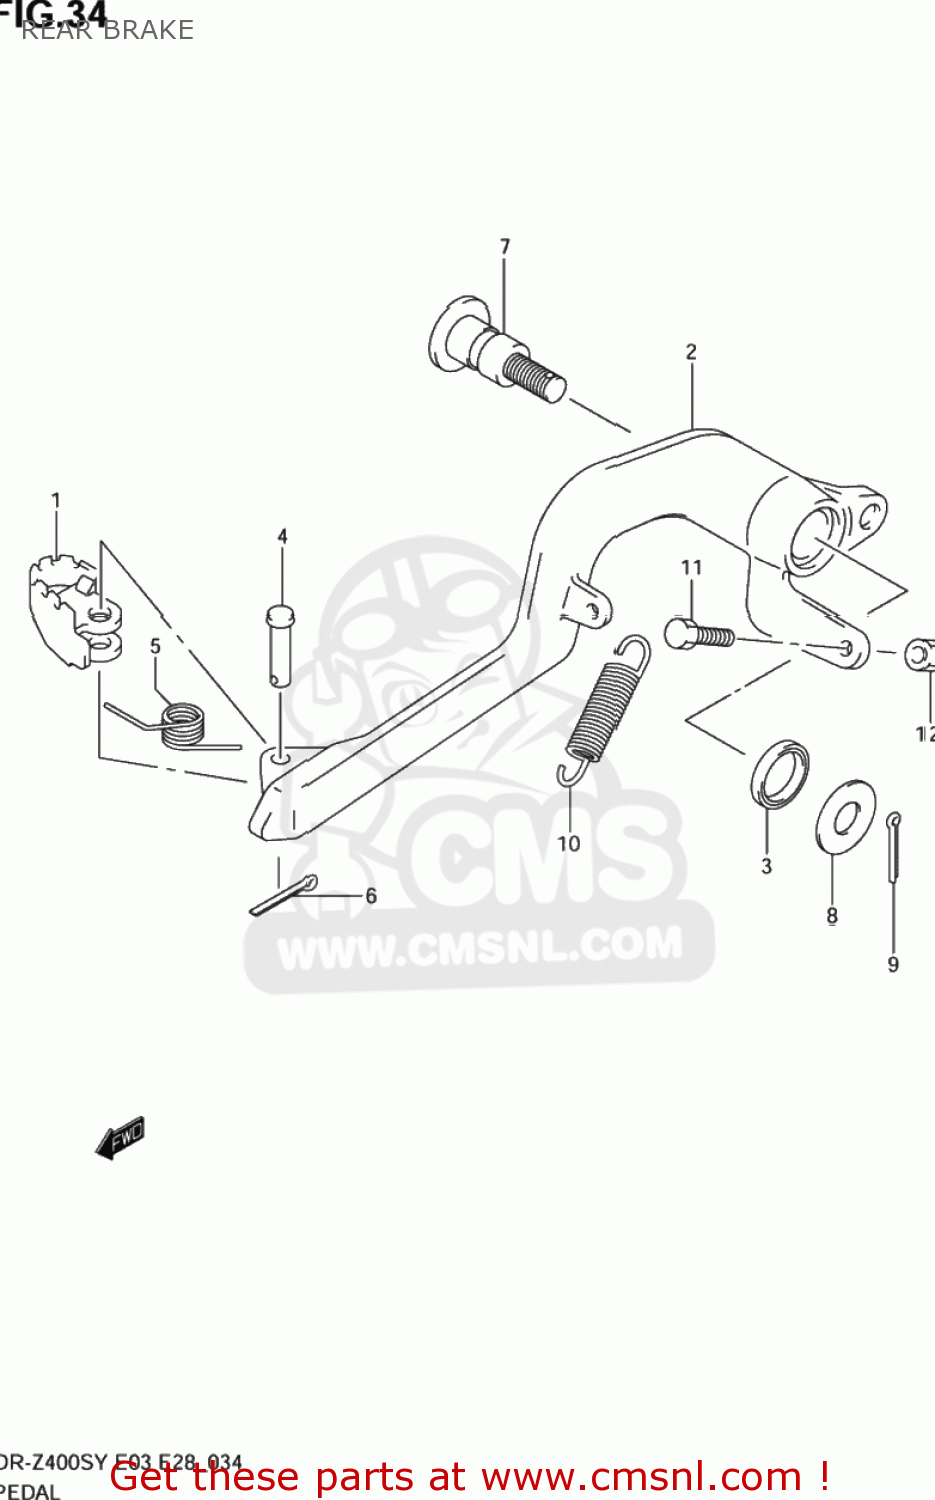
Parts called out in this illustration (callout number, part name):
1	PEDAL,BRAKE
2	ARM,BRAKE PEDAL
3	SEAL,OIL(15X21X3)
4	PIN(6X23.5)
5	SPRING
6	PIN
7	SHAFT,BRAKE PEDAL
8	WASHER
9	PIN 20X20
10	SPRING
11	BOLT(6X30)
12	NUT 6MM
